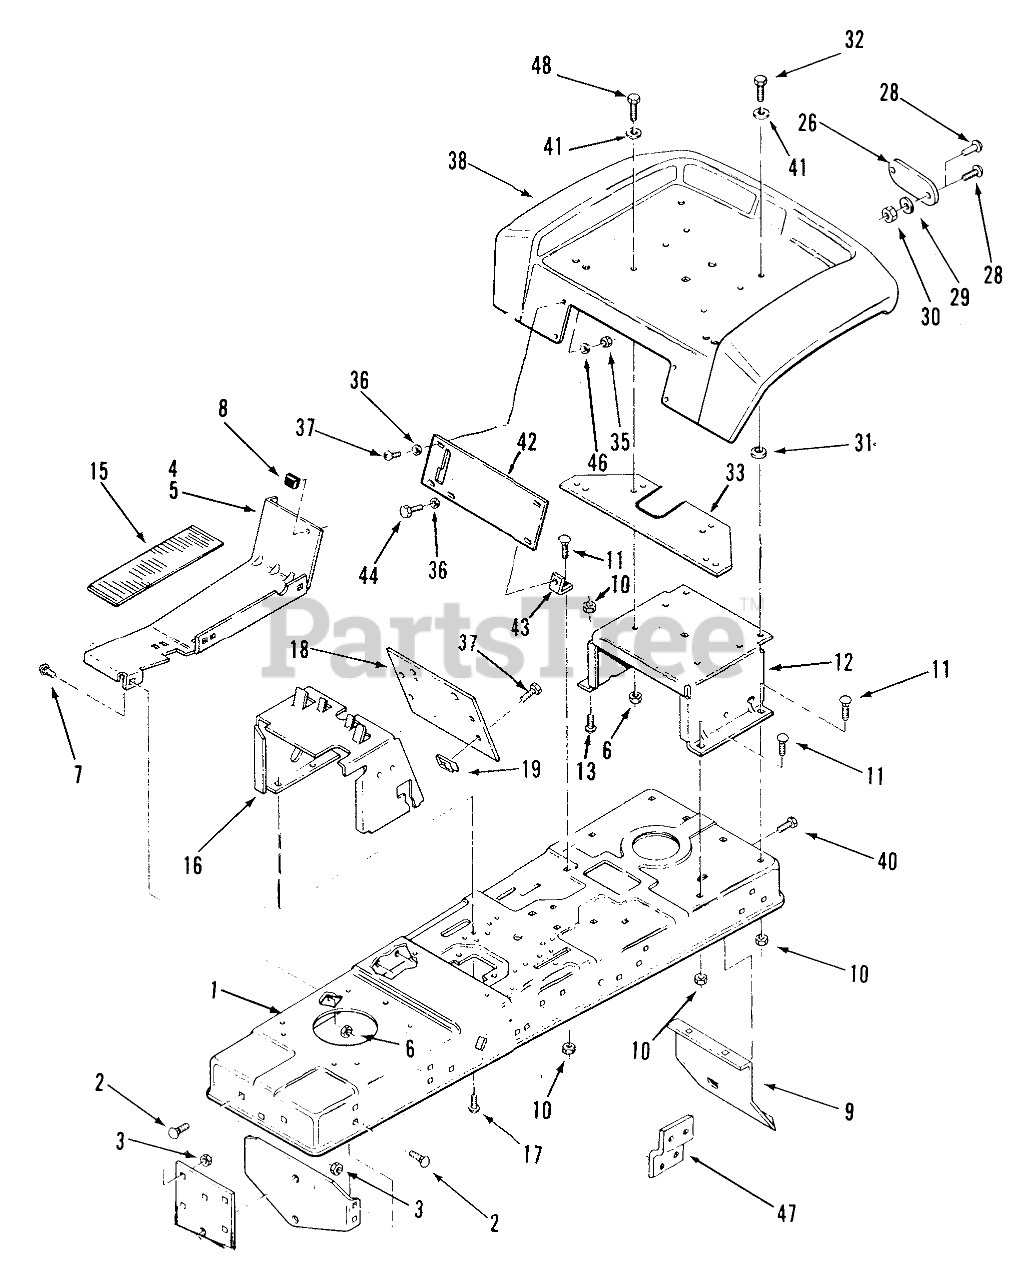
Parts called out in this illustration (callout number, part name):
1	FRAME-B CHASSIS R
2	Bolt
3	Nut
4	RH FOOTREST R
5	Footrest LH
6	Nut
7	Bolt
8	BUMPER
9	Hitch-Drawbar
10	Nut
11	Bolt
12	Support-Seat
13	CARRIAGE BOLT -4
15	PAD-FOOTREST
16	ASS'Y-HOODSTAND B
17	SCREW
18	PLATE-HOODSTAND R B
26	Reflector
28	Poprivet
29	Lockwasher
30	Nut
31	WASHER
32	Bolt
33	PLATE-SEAT R
35	Nut
37	Screw
38	FENDER R
40	Bolt
41	WASHER 5/16 SAE
42	PLATE-SHIFT R
43	BRACKET FENDER
44	Bolt
46	Washer
47	BRKT SWITCH BRAKE R
48	Bolt-Carriage
